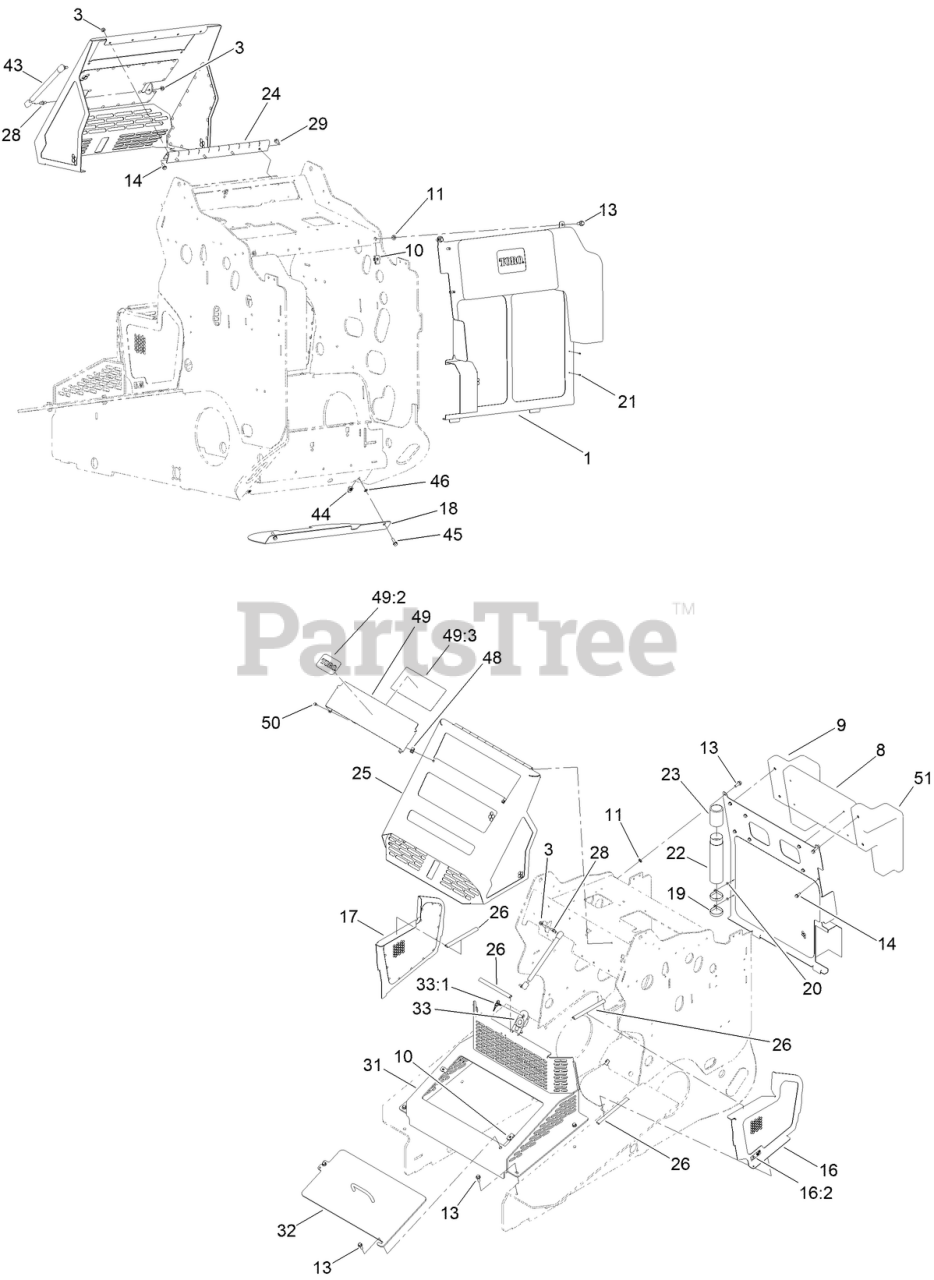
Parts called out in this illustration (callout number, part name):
1	COVER-REAR [BLACK]
3	NUT-HF, NI
8	CUSHION-PAD
9	CUSHION-PAD
10	NUT-TINNERMAN
11	NUT-PUSH
13	SCREW-HHF
14	SCREW-HHF
16:2	DECAL-SURFACE, HOT
17	COVER-SIDE, RH [BLACK]
18	COVER-BOTTOM
19	CLAMP-R
20	WASHER-BACK
21	RIVET-POP
22	TUBE-MANUAL
23	CAP-HOUSING
24	HINGE-HOOD
25	HOOD [BLACK]
26	SEAL-BULB
28	STUD-BALL
29	SCREW-HWHTF
31	COVER-FRONT [BLACK]
32	FRONT COVER ASM, [BLACK]
33	LATCH-COMPRESSION, LOCKING
33:1	KEYS-LATCH
43	SPRING-GAS
44	NUT-CLIP, U
45	SCREW-HHF
46	RING-RETAINING, BOLT
49	HOOD SCOOP ASM
49:3	DECAL-SERVICE
50	SCREW-HWH
51	CUSHION-PAD
